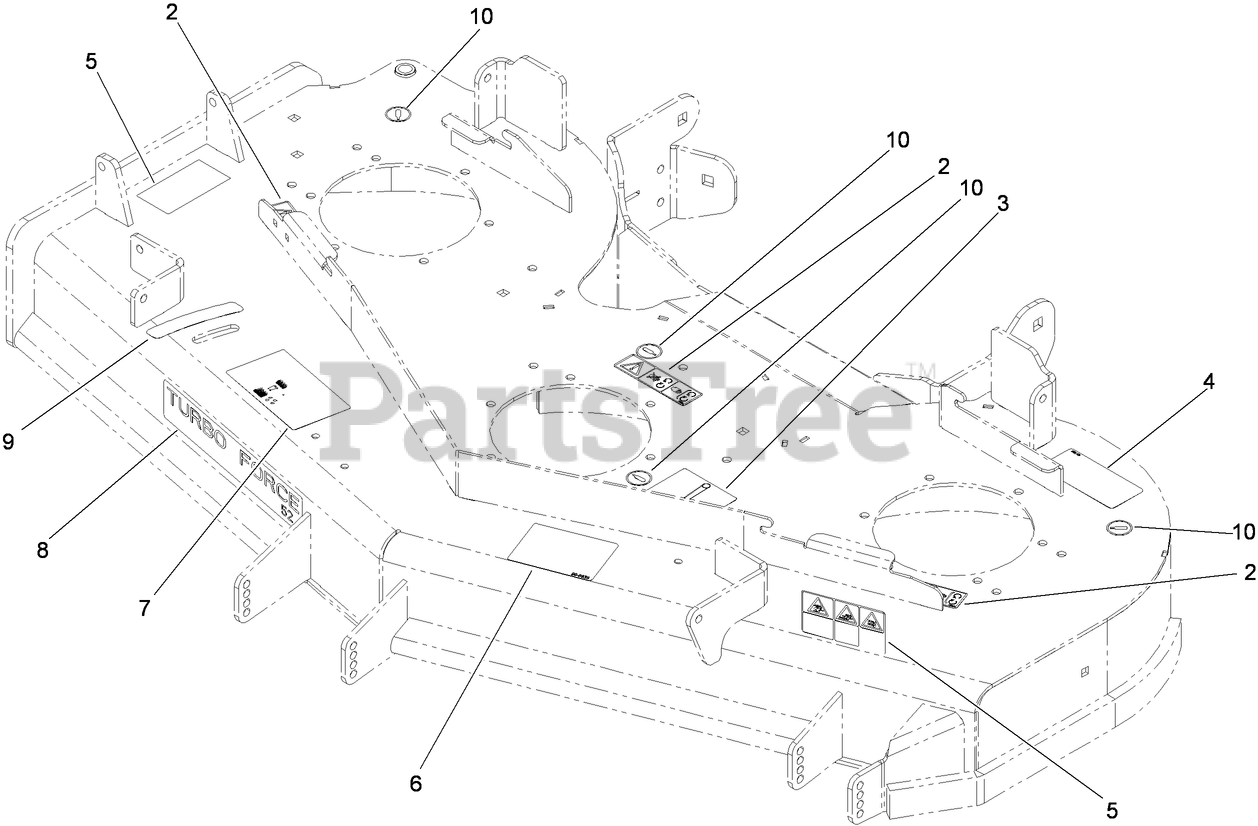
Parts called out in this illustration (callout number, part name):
2	DECAL-MISSING, COVER
3	DECAL-ROUTING, DECK BELT
4	DECAL-TORQUE, BLADE BOLT
5	DECAL-DANGER
6	DECAL-ANTI SCALP
7	DECAL-ADJUSTMENT, BAFFLE
9	DECAL-SETTING, BAFFLE
10	DECAL-GREASE
